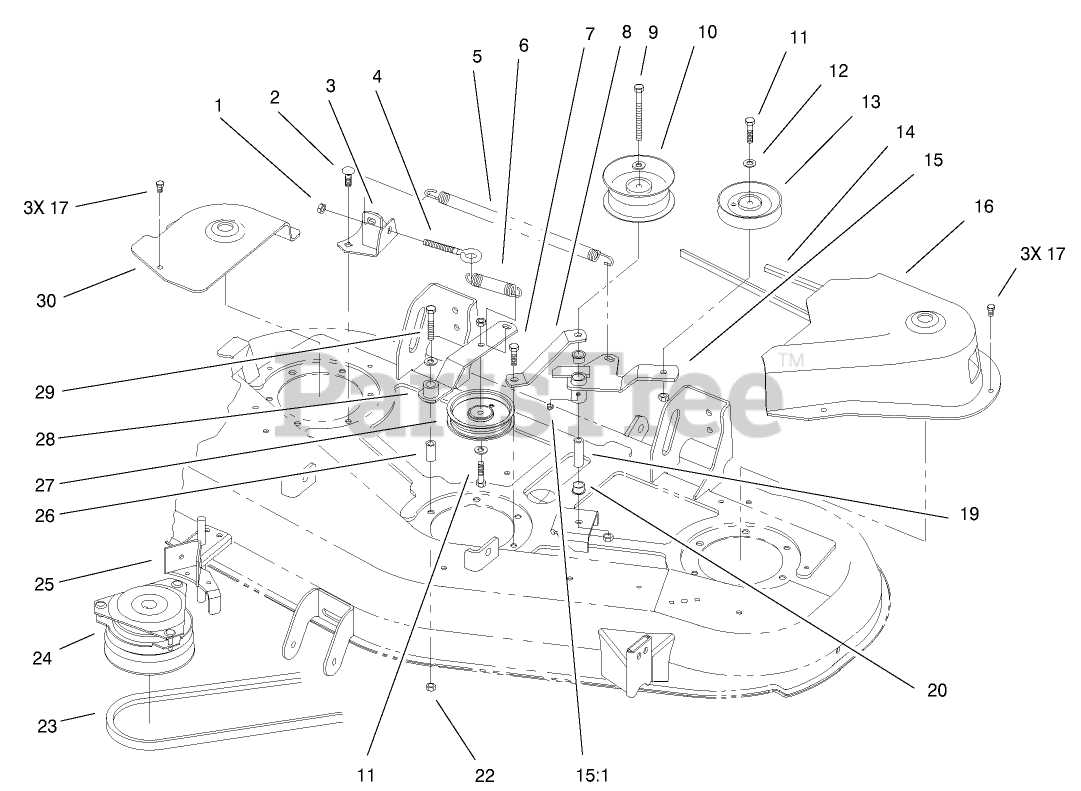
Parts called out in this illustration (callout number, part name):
1	NUT-LOCK, NI
2	SCREW-CARR
3	BRACKET-SPRING
4	BOLT-EYE
5	SPRING-EXTENSION
6	SPRING-EXTENSION
7	SCREW-HH
8	STRAP-SUPPORT
9	SCREW-HH
10	PULLEY-IDLER
11	SCREW-HH
12	WASHER-FLAT
13	PULLEY-IDLER
14	V-BELT
15	IDLER ARM ASSEMBLY
15:1	FITTING-GREASE
16	COVER-BELT, LH
17	SCREW-HHFTF
19	SPACER
20	BUSHING
22	NUT-HF
23	BELT - V
25	DECK UPSTOP ASM
26	SLEEVE
27	PULLEY-IDLER
28	IDLER ARM ASM
29	SCREW-HH
30	COVER - BELT, RH
